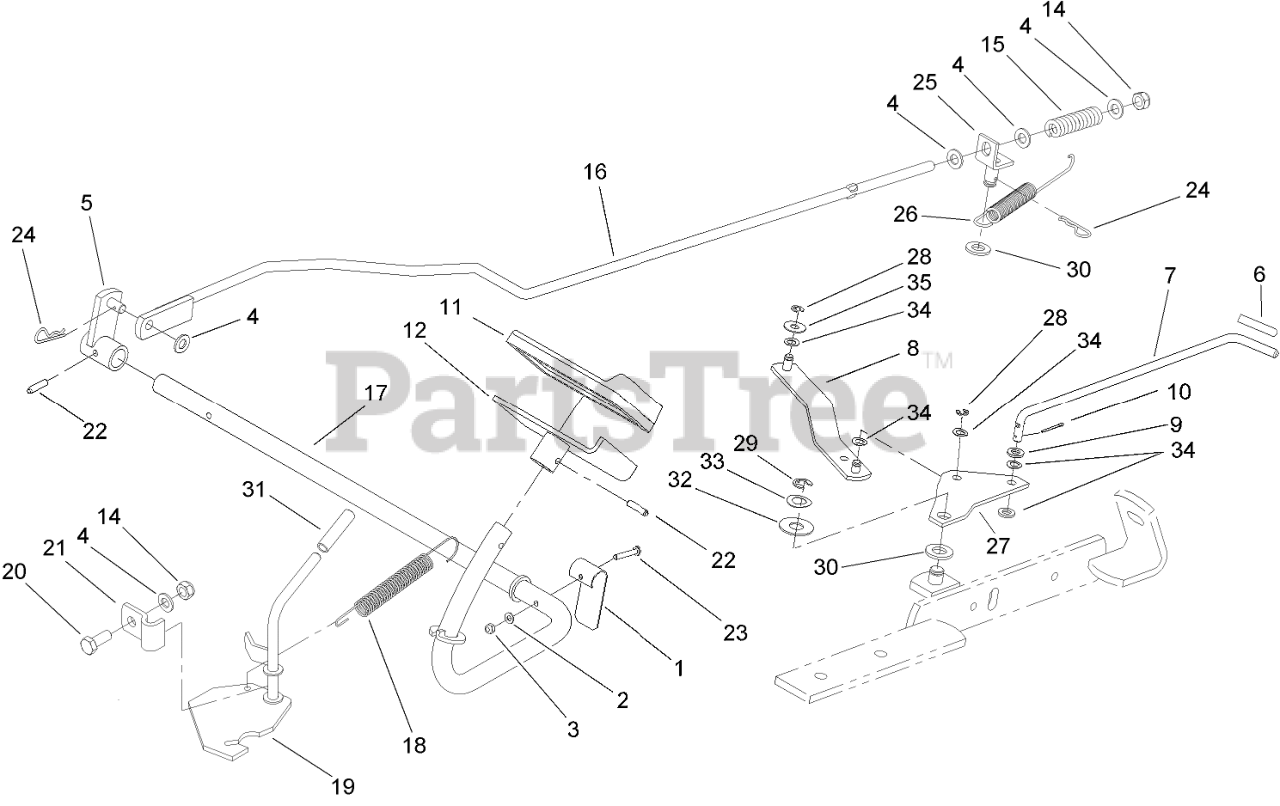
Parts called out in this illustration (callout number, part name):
1	LEVER-SPRING
2	WASHER
3	NUT-HEX
4	WASHER-PLAIN
5	BRACKET-ROD, BRAKE
6	CAP-BYPASS LEVER, HYDRO
7	ROD-LEVER, BYPASS
8	Lever-Bypass
9	WASHER
10	PIN-COTTER
11	PAD-PEDAL
14	NUT-LOCK, NI
15	SPRING-BRAKE
16	ROD-CONNECTING, BRAKE
17	SHAFT-BRAKE
18	SPRING-BRAKE, HAND
19	LEVER-BRAKE, HAND
20	SCREW-HH
21	CLAMP-LEVER, PARKING BRAKE
22	PIN-SPRING
23	SCREW-HEX
24	PIN-COTTER
25	BRACKET-ROD, BRAKE
26	SPRING
27	Plate-Bypass
28	STIRRUP
29	E-CLIP
30	WASHER-FLAT
32	Washer
33	Washer
34	Washer
35	Washer
